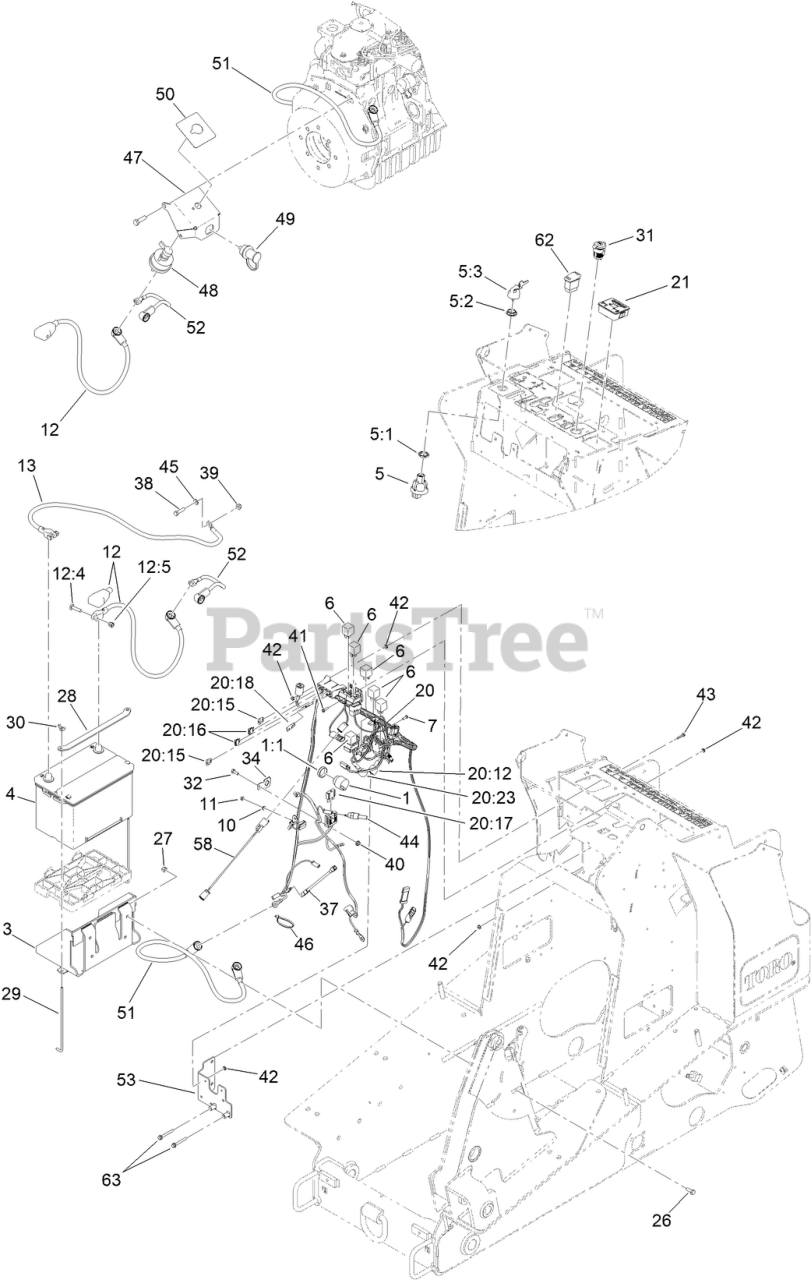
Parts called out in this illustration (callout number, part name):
1	AUDIO ALARM ASM
1:1	NUT-PLASTIC, KNURLED
3	TRAY-BATTERY
4	BATTERY
5	IGNITION SWITCH ASM
5:1	NUT-HEX
5:2	NUT-FACE, M22 (PLASTIC)
5:3	SET-KEY, IGNITION
10	WASHER-LOCK, SPRING
11	NUT-HEX
12	CABLE-BATTERY, POS ASM
12:4	BOLT-BATTERY CLAMP, 5/16-18 UNC
12:5	NUT-CLAMP, BATTERY
13	CABLE-NEGATIVE
20	HARNESS-WIRE, MAIN
20:15	FUSE-BLADE, 10 AMP
20:16	FUSE-BLADE, 15 AMP
20:17	FUSE-BLADE, 50 AMP
20:18	CAP-PLUG
21	MODULE-HOUR METER
26	SCREW-HH
27	NUT-LOCK, NI
28	STRAP-HOLD DOWN, BATTERY
29	ROD-HOLD DOWN, BATTERY
30	NUT-WING
31	RECEPTACLE-12V
32	SCREW-HH
34	CLIP-FUSE
37	HARNESS-LINK, FUSIBLE
38	SCREW-HH
39	NUT-HF, NI
40	NUT-HF
41	SCREW-HWH
42	NUT-KEPS
43	SCREW-HWHTF
44	SWITCH-TEMP
45	WASHER-PLAIN
46	TIE-CABLE
47	MOUNT-REMOTE TERMINAL
48	SWITCH-DISCONNECT, MASTER
49	STUD-JUMPER, POSITIVE
50	DECAL-BATTERY DISCONNECT
51	CABLE-BATTERY, POSITIVE
52	CABLE-BATTERY, POSITIVE
58	HARNESS-WIRE
62	SWITCH-ROCKER, ON-NONE-(ON)
63	SCREW-HHF
